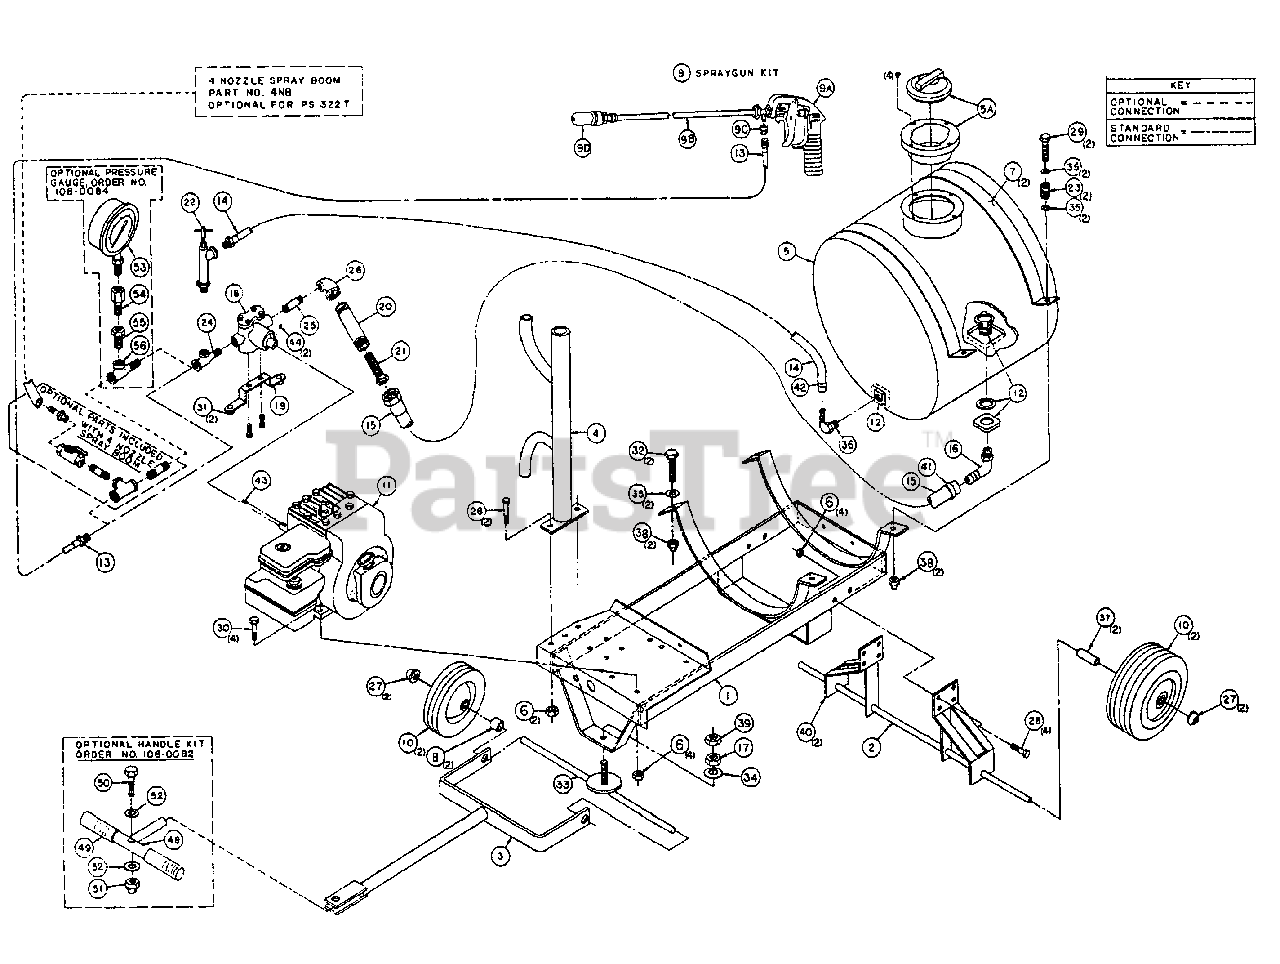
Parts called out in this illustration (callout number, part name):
2	Rear Axle
3	Tow Hitch
4	Hose Rack
5	22 Gallon Tank
5A	Tank Lid & Ring
6	5/16-18 Gripco Locknuts
7	Tank Band
8	Front Wheel Spacer
9	Spray Gun Kit
9A	Spray Gun
9B	Spray Gun Extension
9C	Inlet Adapter
9D	Cone Jet
10	10" Wheel
12	Bulk Head Fitting
13	25' Spray Hose
14	Return Hose 27 1/2" lg
15	Suction Hose 18" lg
16	Nylon Elbow
17	5/8-11 Hex Nut
19	Torque Arm
20	Strainer Nipple
21	Strainer
22	Pressure Relief Valve
24	1/2" Service Tee
25	1/2" x 2" Pipe Nipple
26	3/4" x 1/2" Reducing Elbow
27	Push Nut Cap
28	5/16-18 x 1, HHCS
29	5/16-18 x 2 1/2" HH Tap Bolt
30	5/16-18 x 1-1/2" HHCS
31	Rubber Bumper
32	5/16-18 x 2" HH Tap Bolt
33	Front Axle
34	5/8" Flatwasher
35	5/16" Flatwasher
36	Nylon Elbow
37	2 1/4" Lg Spacer
38	5/16-18 Flex Locknut
39	5/8-11 Hex Half Nut
40	Axle Bracket
41	1/2" Hose Clamp
42	3/8" Hose Clamp
43	1/8" x 3/16" x 1" Shaft Key
44	1/4-28 x 1/4" Set Screw
48	Pull Handle
49	Handle Grip
50	3/8-16 x 1 1/2" HHCS
51	3/8" Flex Locknut
52	3/8" Flatwasher
53	Pressure Gauge
54	Gauge Damper
55	1/2" x 3/8" Bushing
56	1/2" Service Tee
